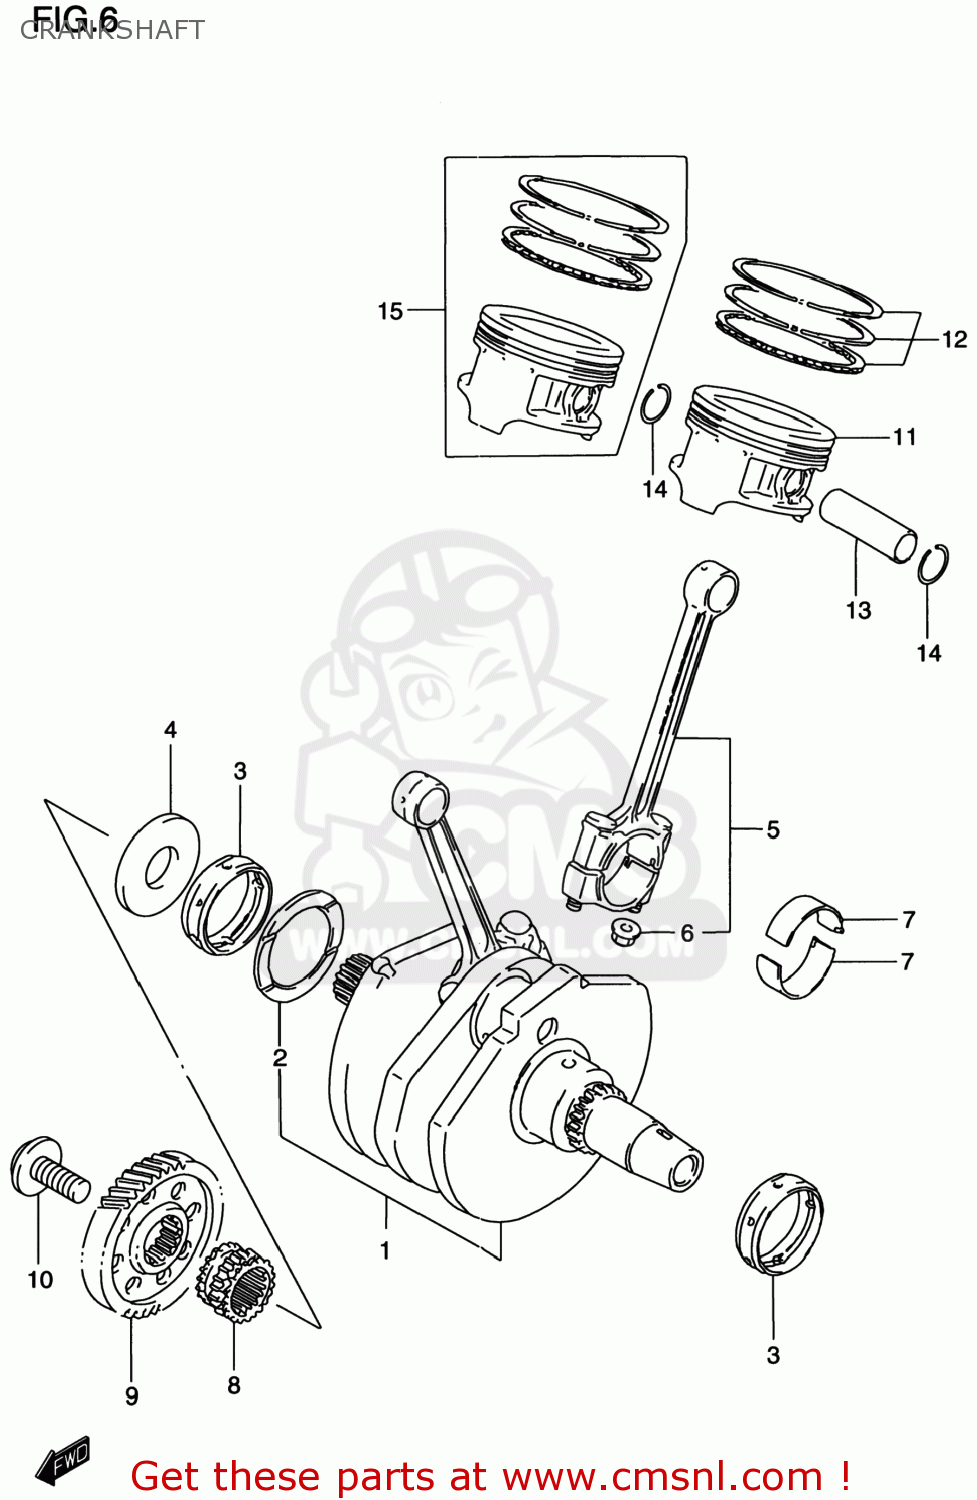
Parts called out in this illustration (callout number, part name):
1	CRANKSHAFT SET
2	WASHER(48.1X64X1.94)
3	METAL,CRANKSHAFT
4	WASHER,CRANK THRUST
5	CONNECTING ROD ASSY
6	NUT
7	BEARING,CRANK PIN
8	SPROCKET,CAM CHAIN DRIVE,R
9	GEAR,PRIMARY DRIVE
10	BOLT(12X28)
11	PISTON
12	RING SET,PISTON
13	PIN,PISTON
14	CIRCLIP,PISTON PIN
15	PISTON SET(OS:0.5)
